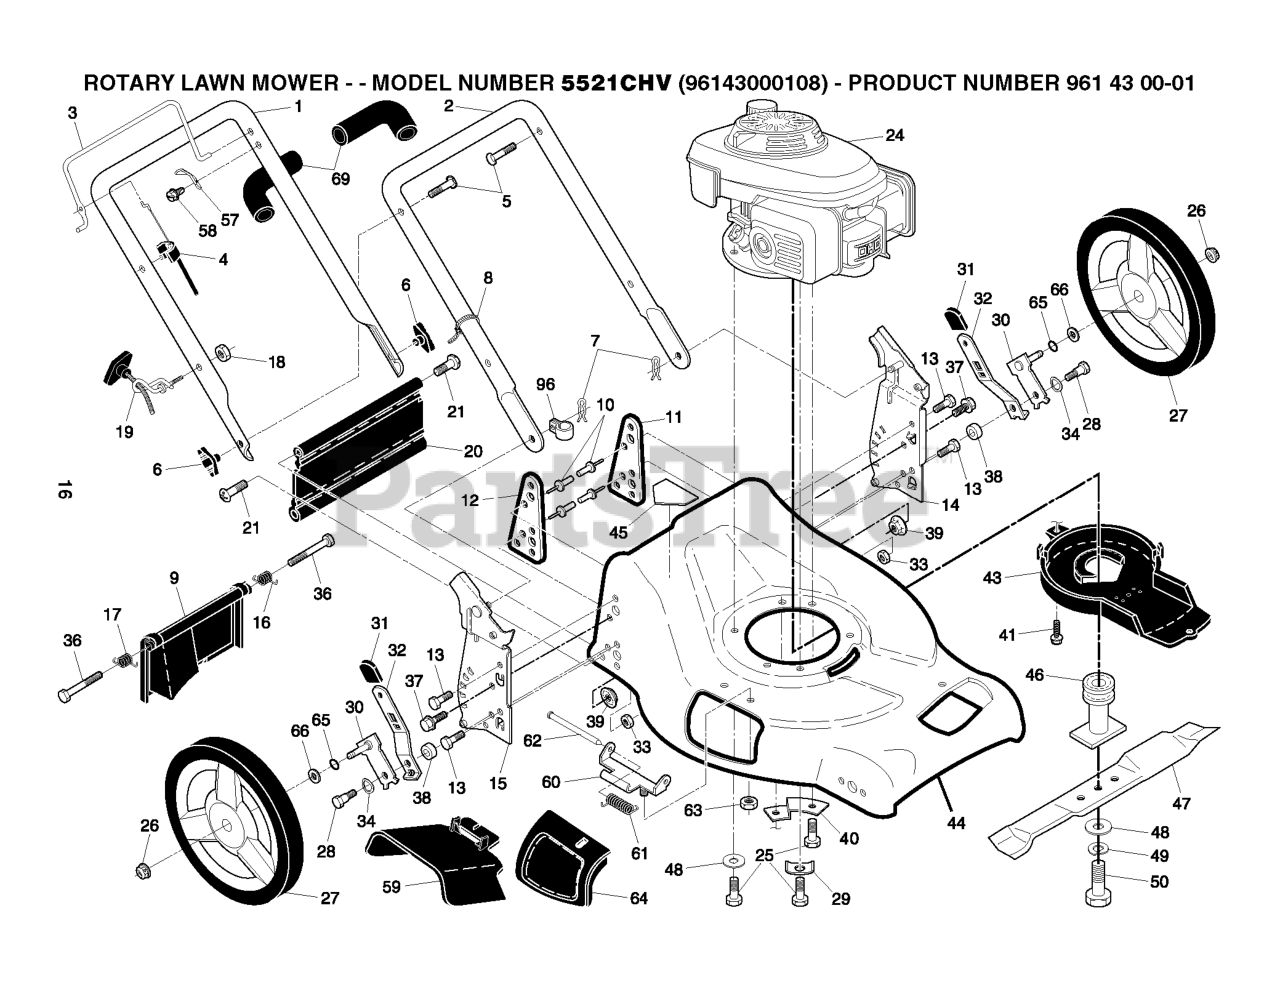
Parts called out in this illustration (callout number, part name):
1	HANDLE.UPER.D.ST.EZ
2	LOWER HANDLE
3	BAIL.DSTRT.FL.AW.CREAS.ORANGE
4	CABLE.ENGINE BRAKE.MZR
5	BOLT, HANDLE 5/16-18X1.75
6	HNDL.KNOB.GRAY
7	HAIRPIN COTTER
8	TIE GUIDE
9	REAR DOOR ASSEMBLY
10	RIVET BLIND
11	SUPPORT BRACKET LH
12	BRACKET.SUPRT.RH.21.FWGD
13	SCREW 14-20 X 5/8
14	BRKT.ASM.HNDL.21FGD.EZ
15	BRKT.ASM.HNDL.21FGD
16	SPRING.REAR.DOOR.EZ.21.LT
17	SPRING.REAR.DOOR.EZ.21.RT
18	NUT
19	RB GUIDE.ROPE.STD.BLK.ZIN WSL
20	SKIRT.REAR.21 FWGD.BLACK
21	HINGE SCREW
25	BOLT 3/8-16X1-1/8
26	NUT.HEX.FLANGE.3/8-16.LOCKNUT
27	WHEEL ASSY
28	SHOULDER BOLT 5/16-18
29	WASHER.ENGINE.BZP
30	ARM.ASM.AXLE.REAR.5/9.POS.BZP
31	SELECTOR KNOB
32	SELECTOR SPRING
33	NUT.71038.31-18.HEX.NYLOCK
34	WASHER.CURVED.CYLINDRICAL
37	BOLT.FIN.HEX.5/16-18X3/4
38	SPACER.HEIGHT.ADJUSTER
39	NUT.FLANGE.5/16
40	BRACKET
41	SCREW.HEX.WSH
43	DEBRIS SHIELD
44	HOUSING.21.FWD.ORANGE.WALK
45	DANGER DECAL
46	RP ADAP.BLDE/PULL
47	BLADE.21.PUSH/RWGD/FWGD
48	WASHER,HARDEN
49	LOCKWASHER
50	SCREW, HEX HD 3/8-24 X 1-3/8
57	BRACKET UPSTOP
59	DEFLECTOR.CLIPPIN.21.FGD
60	BRACKET.ASM.HINGE.21.FWGD.
61	SPRING.TORSION
62	ROD.HINGE.21
63	LOCKNUT.NYLOC.1/4-20
64	DOOR.MULCH.21.REAR.FWGD
65	O-RING..070X.487.NEOPRENE
66	WASHER.FLAT.1/2
69	GRIP.HANDLE.FOAM.WIDE.(1 SIDE)
96	CLIP.CABLE.BLK
